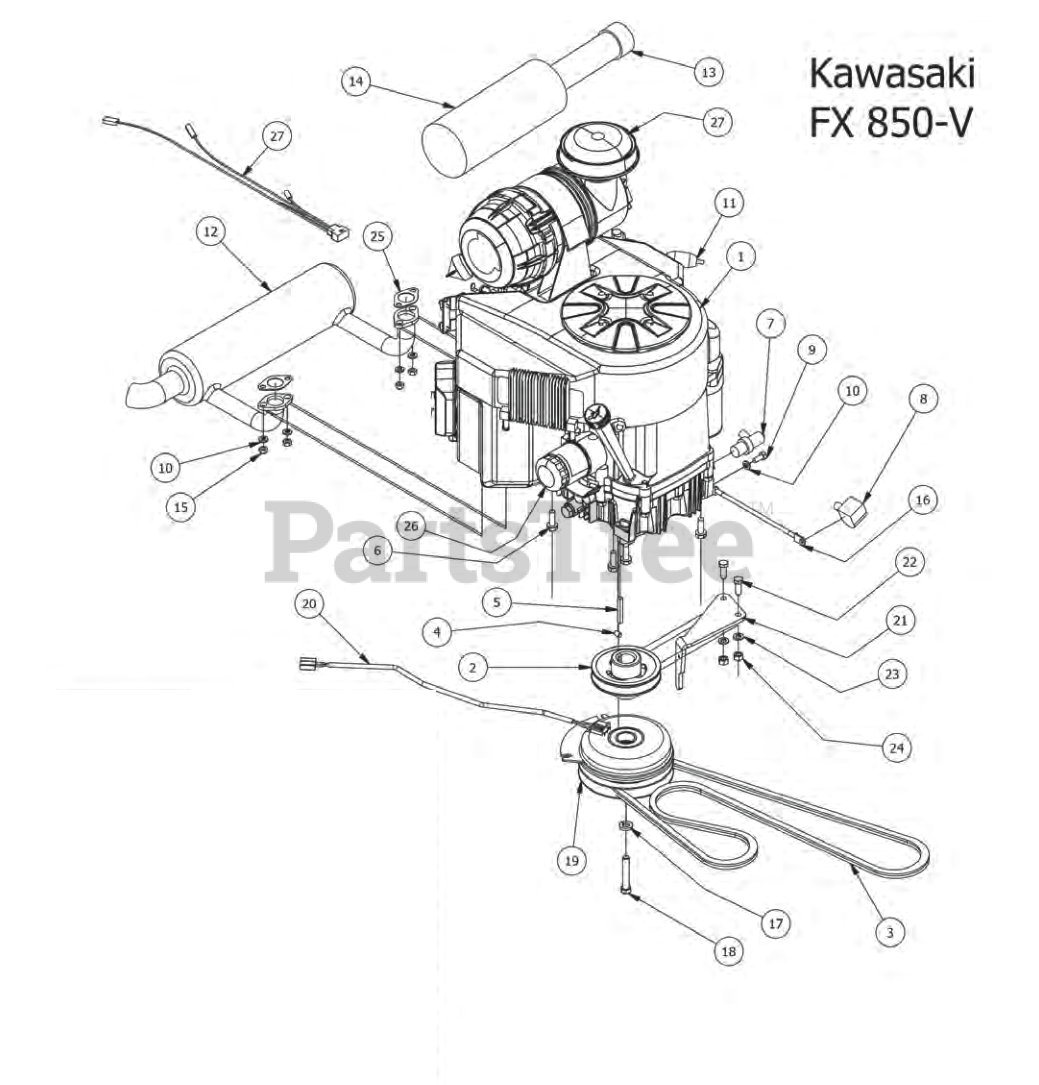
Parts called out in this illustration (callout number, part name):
1	Kawasaki Engine FX-850-V-CS09R
2	4 3/4 Motor Pulley
4	3/8" Set Screw
5	1/4 x 2 Square key Stock
6	3/8 x 1 1/8 bolt
8	Black Boot For ground cable
9	M8x1.20x20MM Hex head bolt
10	5/16" Lock Washer
11	Universal inline Fuel Filter
12	Kawasaki Exhaust
13	Canister Air Filter- Inner
14	Canister Air Filter-Outer
15	M8-1.25 Zinc Nut
16	Starter to chassis cable
17	7/16" Lock Washer
18	7/16" x 2 1/2" Hex Bolt
19	Clutch Assembly
20	Clutch Pigtail
21	PTO Engager Holder
22	3/8" x 1" Hex Bolt
23	3/8" Lock Washer
24	3/8" Hex Nut
25	Exhaust gasket
26	Kawsaki Oil Filter
27	Kawasaki Rain Cap
28	Harness Adaptor - Outlaw FX (All)
